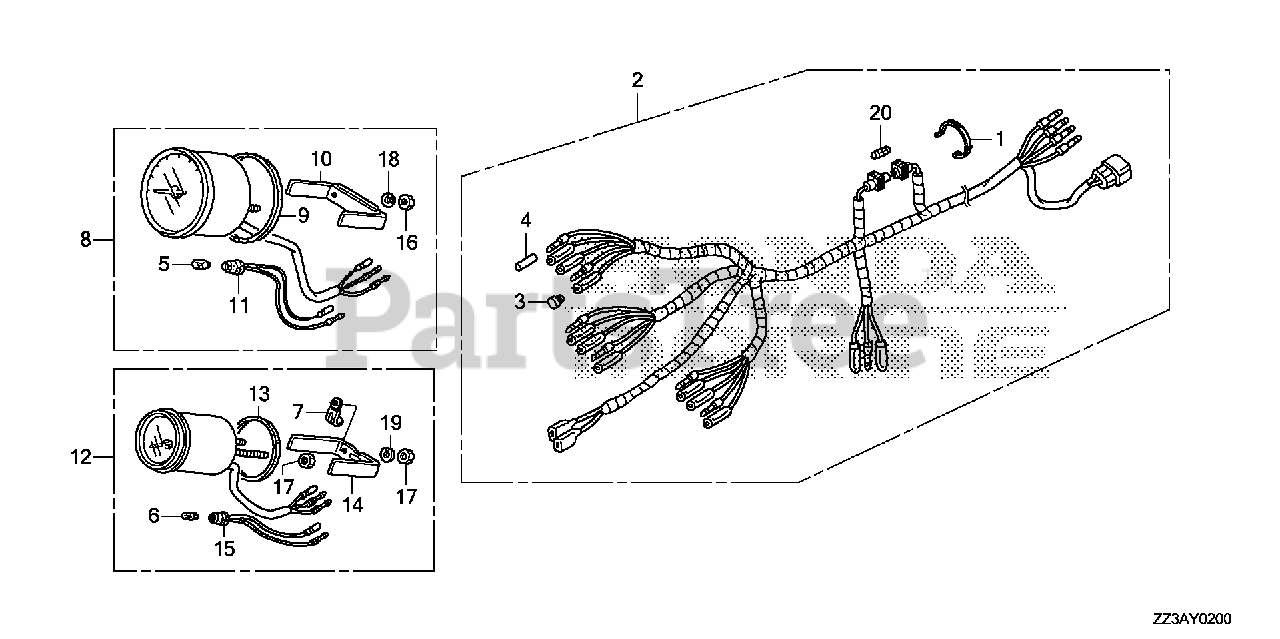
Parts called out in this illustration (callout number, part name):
1	BAND B1, WIRE
2	HARNESS ASSY., METER (A)
3	PLUG, CONNECTOR (INNER)
4	PLUG, CONNECTOR (OUTER)
5	BULB, WEDGE BASE (T10) (12V 1.7W) (STANLEY)
6	BULB, WEDGE BASE (12V 1.7W)
7	CLAMP
8	TACHOMETER ASSY.
9	GASKET
10	BRACKET
11	SOCKET
12	METER ASSY., TRIM
13	GASKET
14	BRACKET
15	SOCKET
16	NUT, HEX. (5MM)
17	NUT, HEX. (4MM)
18	WASHER, SPRING (5MM)
19	WASHER, SPRING (4MM)
20	FUSE A (10A)
